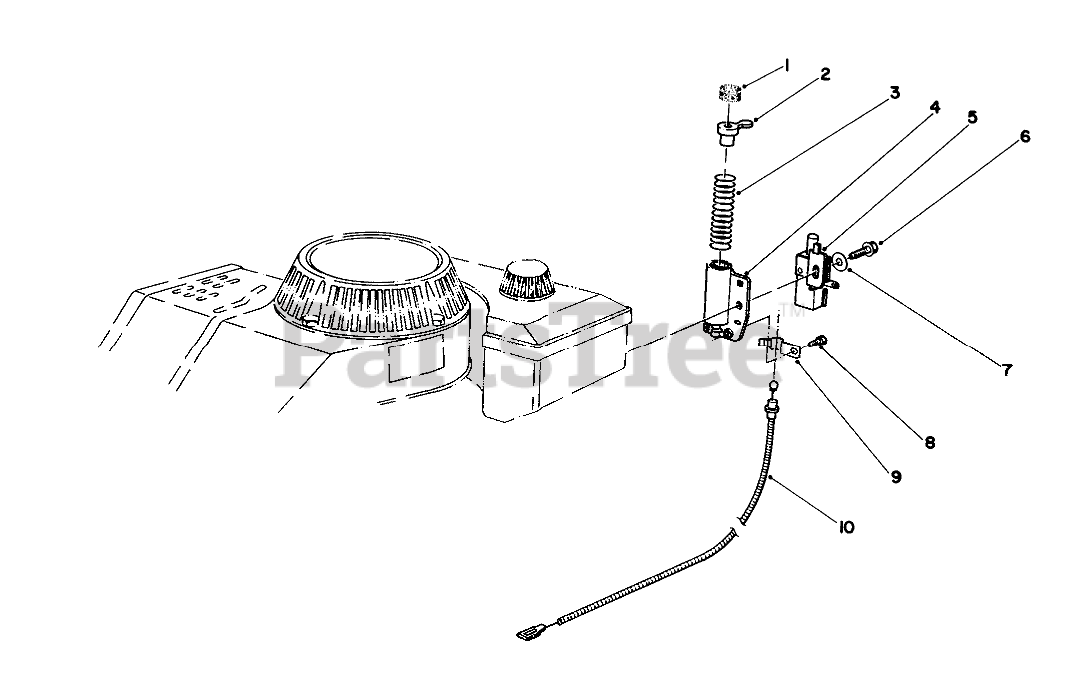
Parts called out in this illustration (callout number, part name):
1	Pad-Friction
2	Plunger & Pad Assembly (Incl. Ref. #1)
3	COMP SPRING
4	TUBE W A
5	PUSH BUTTON SWITCH
6	Screw
7	WASHER-FLAT
8	SCREW
9	CABLE CLAMP
10	BRAKE CABLE
